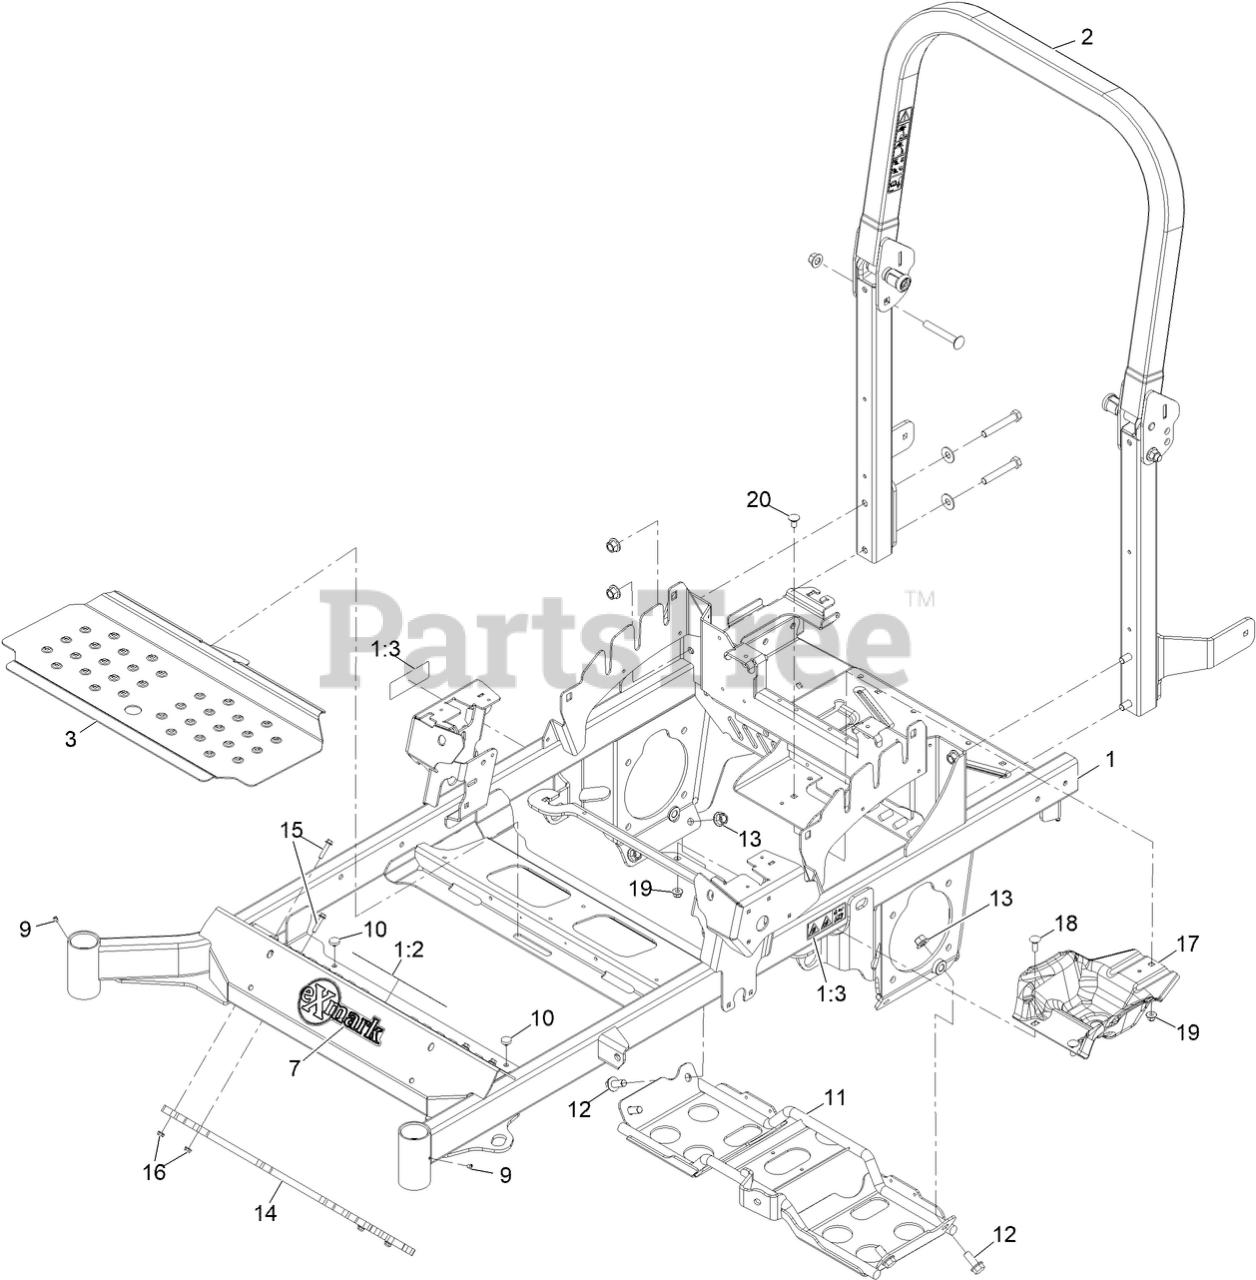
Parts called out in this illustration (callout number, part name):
1	ASM, Frame W/ Decal
1:2	DECAL-DANGER
1:3	DECAL-WARNING
2	ASM, ROPS
3	Pan, Floor
7	DECAL-EXMARK
11	Weld, Skid Plate
12	SCREW-HHF
13	Nut-Lock 1/2-13
14	Weight-Toe Board
15	SCREW-HHF
17	Guard-Sump
18	Screw-CARR
19	NUT-HF, NI
20	SCREW-CARR
